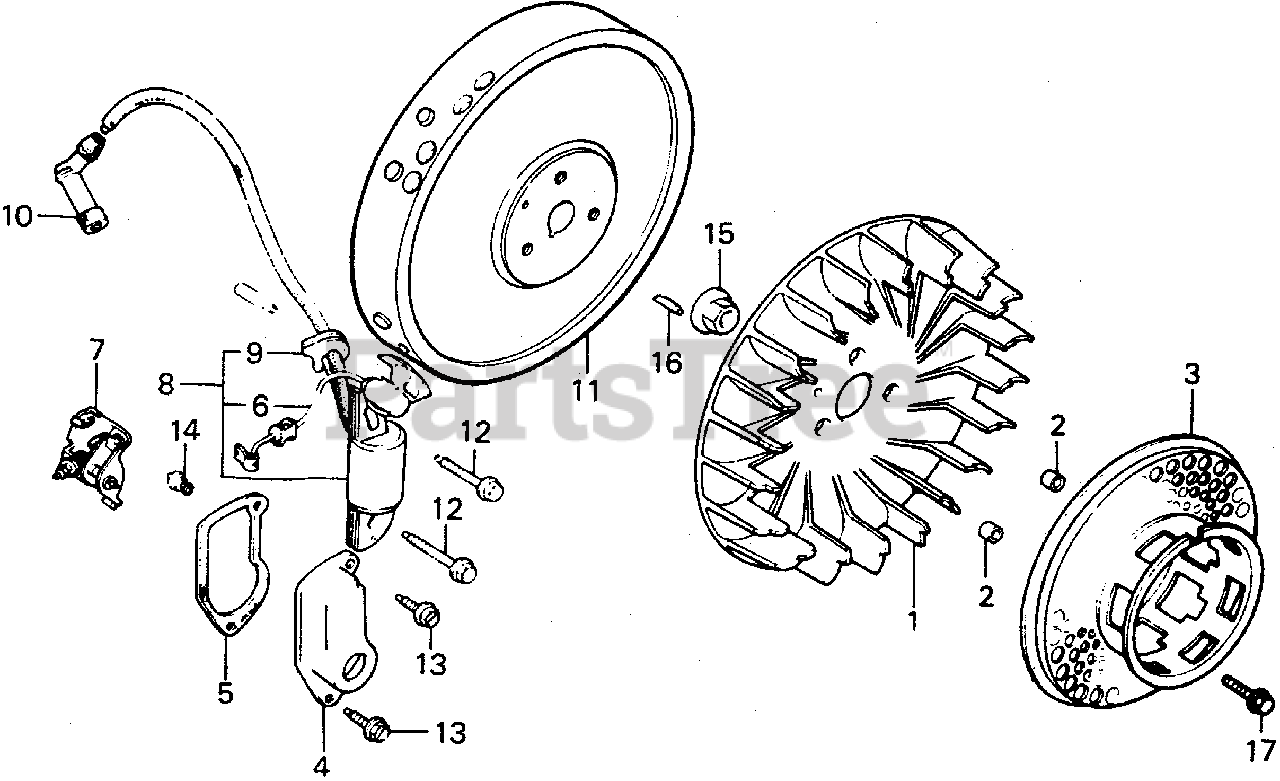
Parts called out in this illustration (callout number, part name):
1	FAN, COOLING
2	COLLAR, FAN
3	PULLEY, STARTER
4	COVER, BREAKER
5	GASKET, POINT COVER
6	CONDENSER
7	POINTS ASSY.
8	COIL ASSY., IGNITION
9	GROMMET, WIRE
10	CAP ASSY., NOISE SUPPRESSOR
11	FLYWHEEL (POINT)
12	BOLT, FLANGE (6X32)
13	BOLT, FLANGE (5X10)
14	SCREW-WASHER (5X12)
15	NUT, SPECIAL (14MM)
16	KEY, WOODRUFF (25X18)
17	BOLT, FLANGE (6X16)
